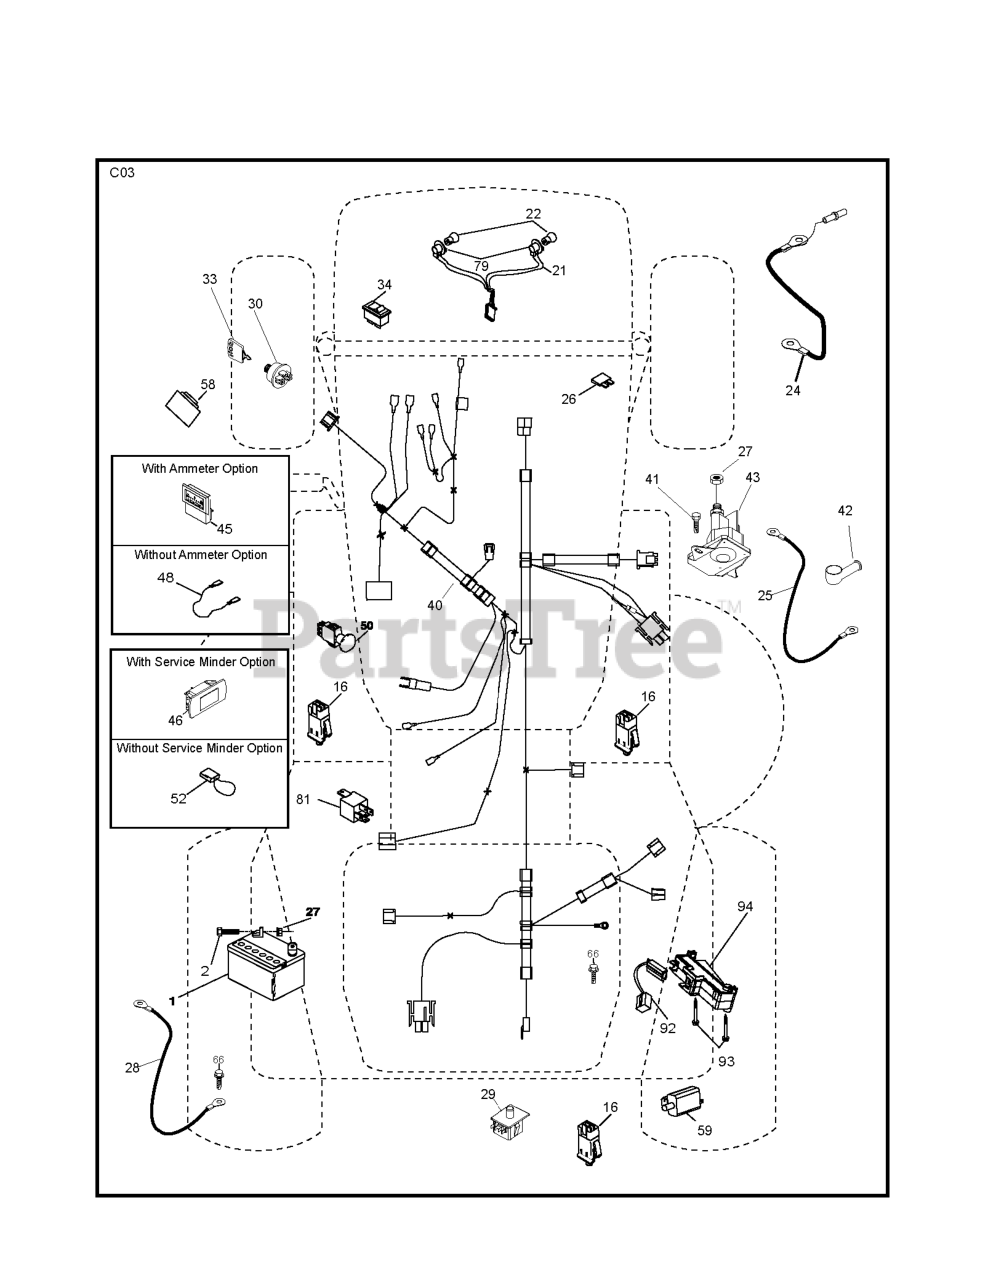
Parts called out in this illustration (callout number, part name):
1	Battery 12 Volt 25 Amp
2	BOLT.HEX.1/4.X.3/4.DICHROMATE
16	SWITCH INTERLOOK PUSH-IN
21	HARNESS.LIGHT W/4152J BULBS
24	BATTERY CABLE GT
25	CABLE BATTERY
26	FUSE 20AMP
27	NUT
28	CABLE GROUND
29	SWITCH.SEAT.DP W/RAMPS
30	SWITCH.IGN.DELTA.W.LGH.ROS
33	KEY.CHAIN.BLISTER.PACK.GEN.INT
40	RP HARNESS.IGN.ELECT.REG.CRD
41	BOLT
42	TERMINAL COVER
43	SOLENOID.W/BRASS.PLUNGER
48	ADAPTER.AMMETER
50	RP.PTO.SWITCH.8 TERMINAL.BLACK
58	BUZZER
59	.WITCH.FULL BAGGER.INDICATOR
79	BULB HOLDER ASM.
81	RELAY.ASSY.T
92	HARNESS.PIGTAIL.CONSLE
93	SCREW.PLASTITE
94	MODULE.REVERSE.ROS
